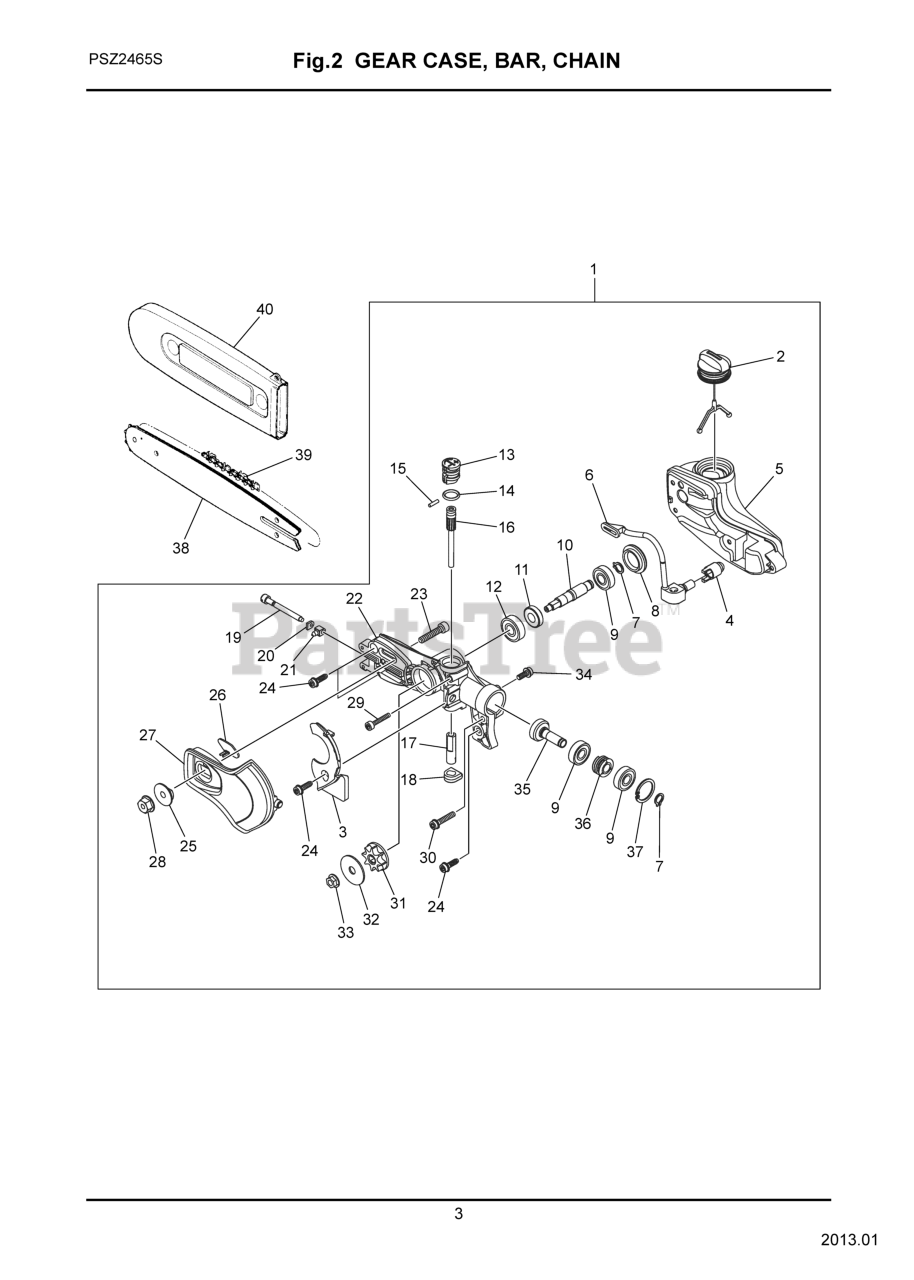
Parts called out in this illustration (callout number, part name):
1	POLE SAW HEAD
2	TANK CAP ASSY
4	OIL SCREEN
5	OIL TANK ASSY
6	OIL HOSE
7	RETAINING RING
11	GEAR WHEEL
12	BALL BEARING
15	NEEDLE ROLLER
16	%PUMP PISTON
17	PUMP CYLINDER
18	FASTENER
22	GEAR HOUSING
23	SCREW IHSCM
28	HEXAGON NUT FLANGED
29	SCREW ITXSCM
31	SPUR SPROCKET
33	FLANGE NUT
36	WORM GEAR
37	RETAINING RING
38	BAR 12" (FITS: PS2401) PS0011
39	CHAIN 19VG-J44E
